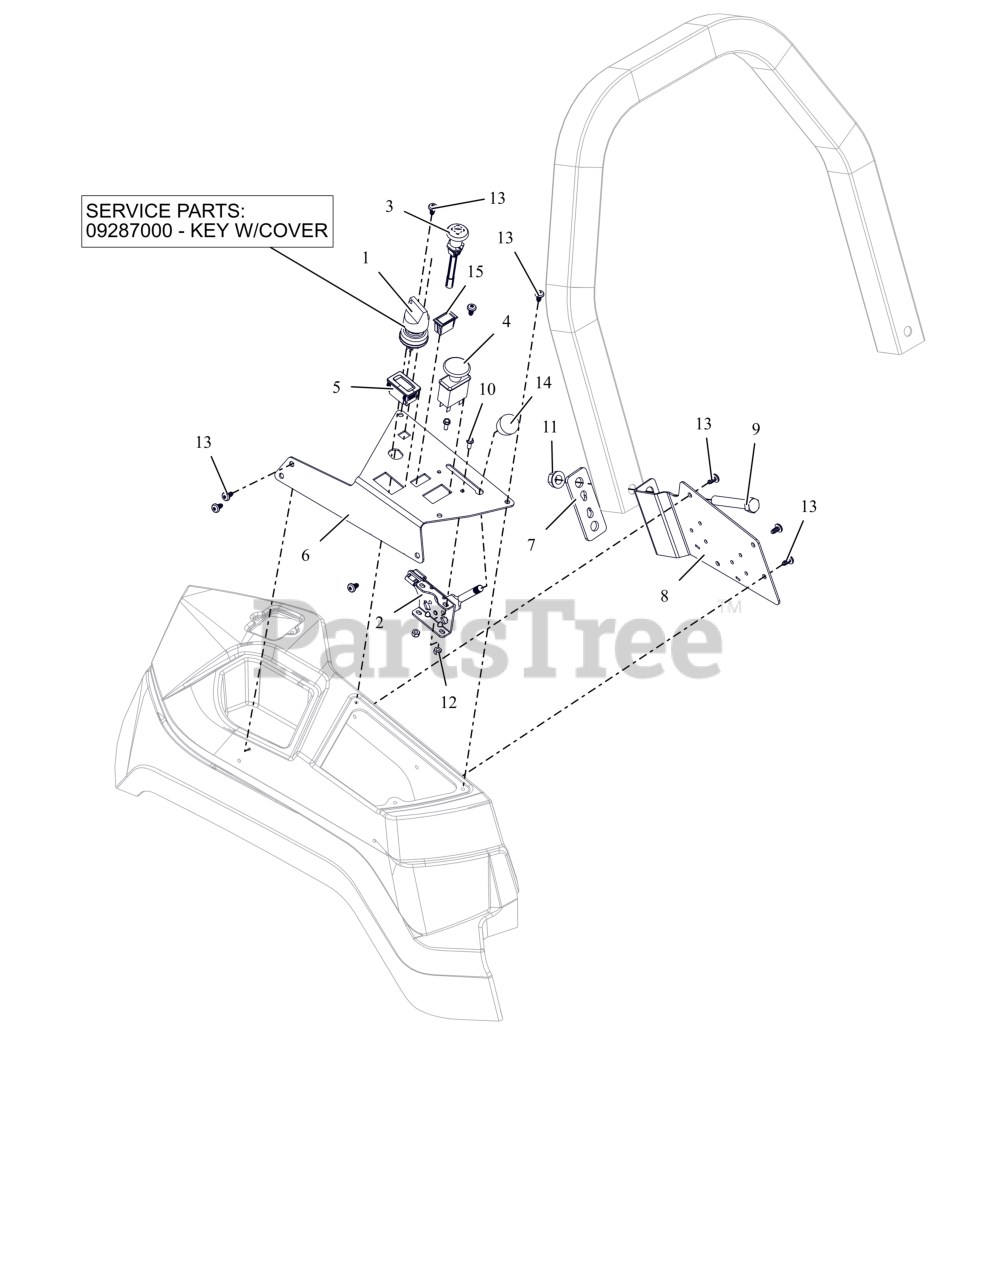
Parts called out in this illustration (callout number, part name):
1	SWITCH, IGNITION
1	KEY, W/ SHIELD
2	CABLE, PRO THROTTLE CONTROL
3	CABLE - CHOKE, SNAP-IN
4	SWITCH, CLUTCH
5	HOUR METER
6	PLATE, APEX CONTROL PANEL
7	PLATE, CONTROL PANEL SPACER
8	BRKT, FENDER/RELAY MOUNTING
9	BLT, HEX .50-13X3.00 G5 ZCC
10	BLT, HWH #10-24X.50 ZCC
11	NUT-LK-CTR-FLG .500-13 GG ZCC
12	NUT-LK-NYL #10-24 G2 ZCC
13	SCR-PAN .25-15X.50 6L H/LZB500
14	KNOB-CONTROL-BLACK .38-16X.50
15	SWITCH,BLANK
